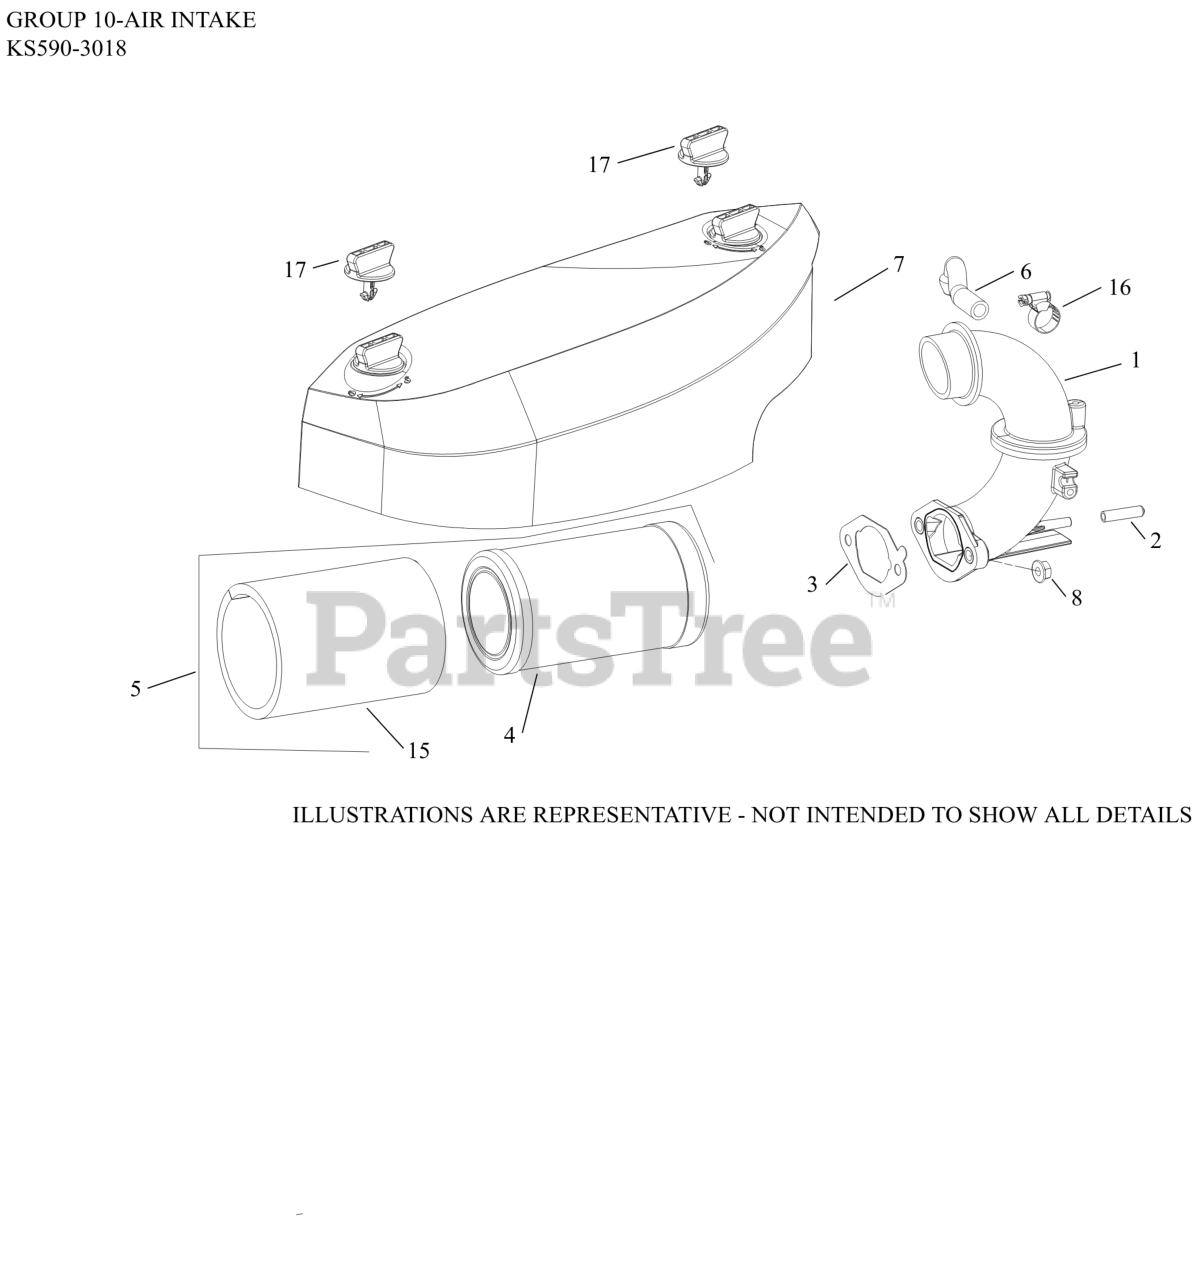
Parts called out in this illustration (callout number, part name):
1	ADAPTER, AIR CLEANER ASSY
2	CAP, MASKING
3	GASKET, CARBURETOR
4	ELEMENT, AIR FILTER
5	AIR FILTER KIT (STD)
6	HOSE, BREATHER
7	COVER, AIR CLEANER ASSY
8	NUT, FLG M6X1.0
15	ELEMENT, PRE-CLEANER
16	CLAMP, HOSE (KM)-USE 25 237 31-S
17	KNOB, AIR CLEANER COVER
